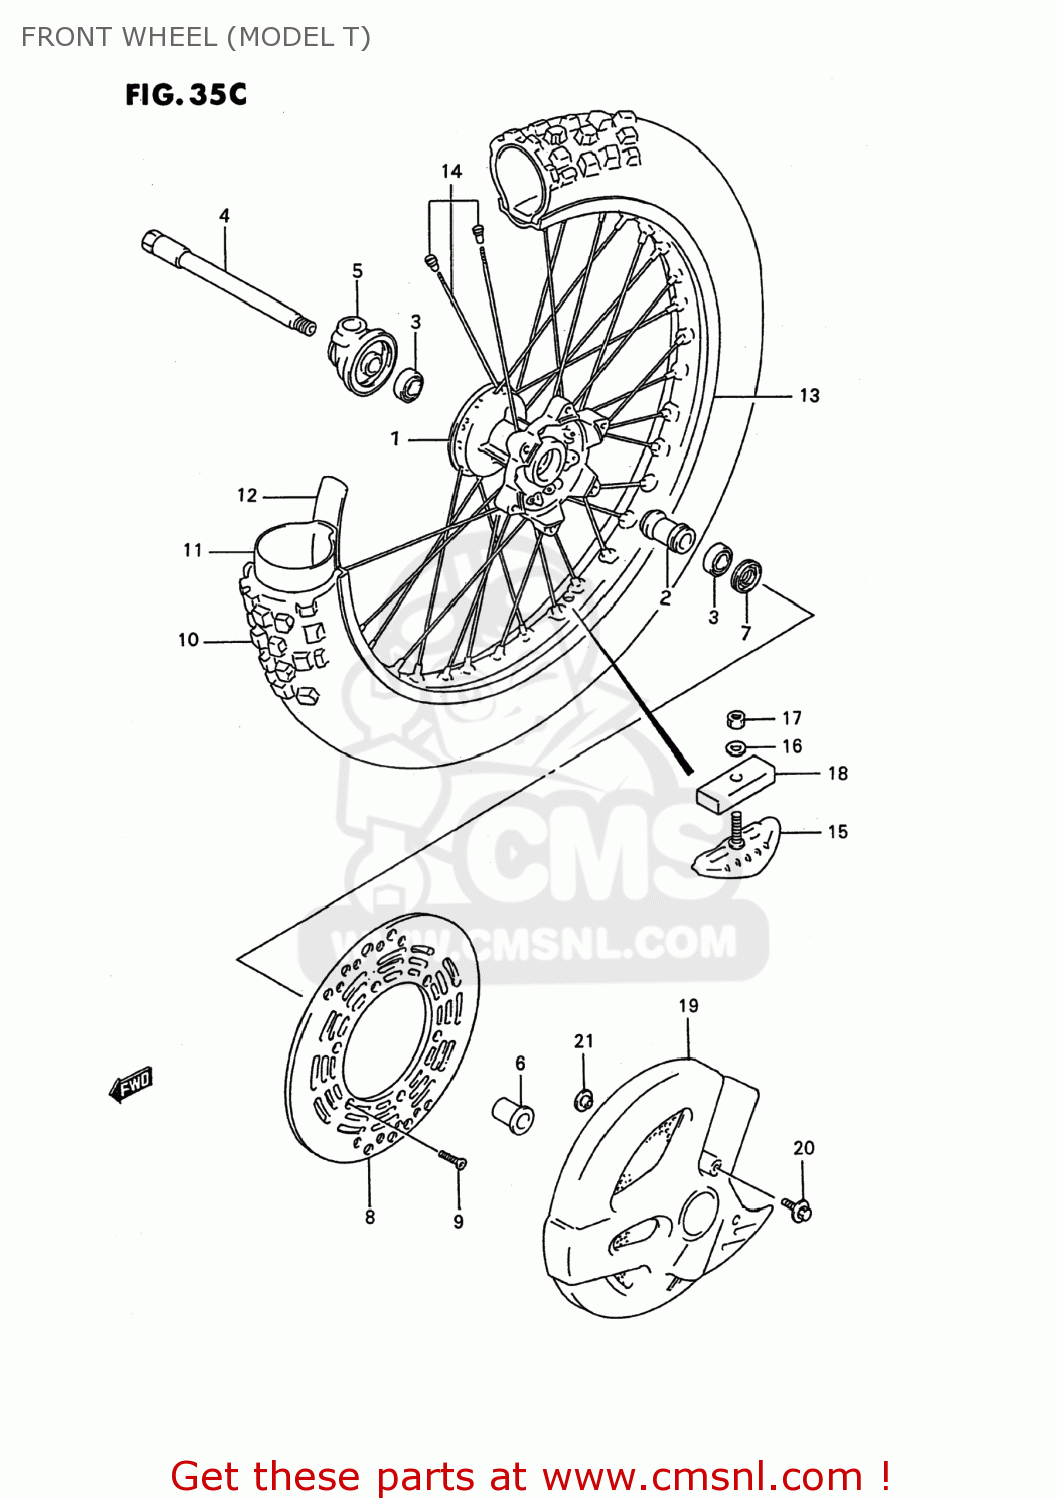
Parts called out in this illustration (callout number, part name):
1	HUB,FRONT WHEEL
2	SPACER,FR HUB BEARING
3	BEARING
4	AXLE,FR
5	BOX ASSY,SPEEDOMETER GEAR
6	SPACER,FR AXLE,L
7	SEAL,OIL(23X35X6)
8	DISC,FR BRAKE
9	SCREW
10	TIRE,FRONT 80/100-21
11	TUBE
12	PROTECTOR,WHEEL INNER
13	RIM,FRONT WHEEL (1.60X2
14	SPOKE SET,FR WHEEL
15	STOPPER,BEAD
16	WASHER
17	NUT
18	CUSHION,BEAD STOPPER
19	COVER,FRONT BRAKE DISC
20	BOLT(6X16)
21	WASHER
